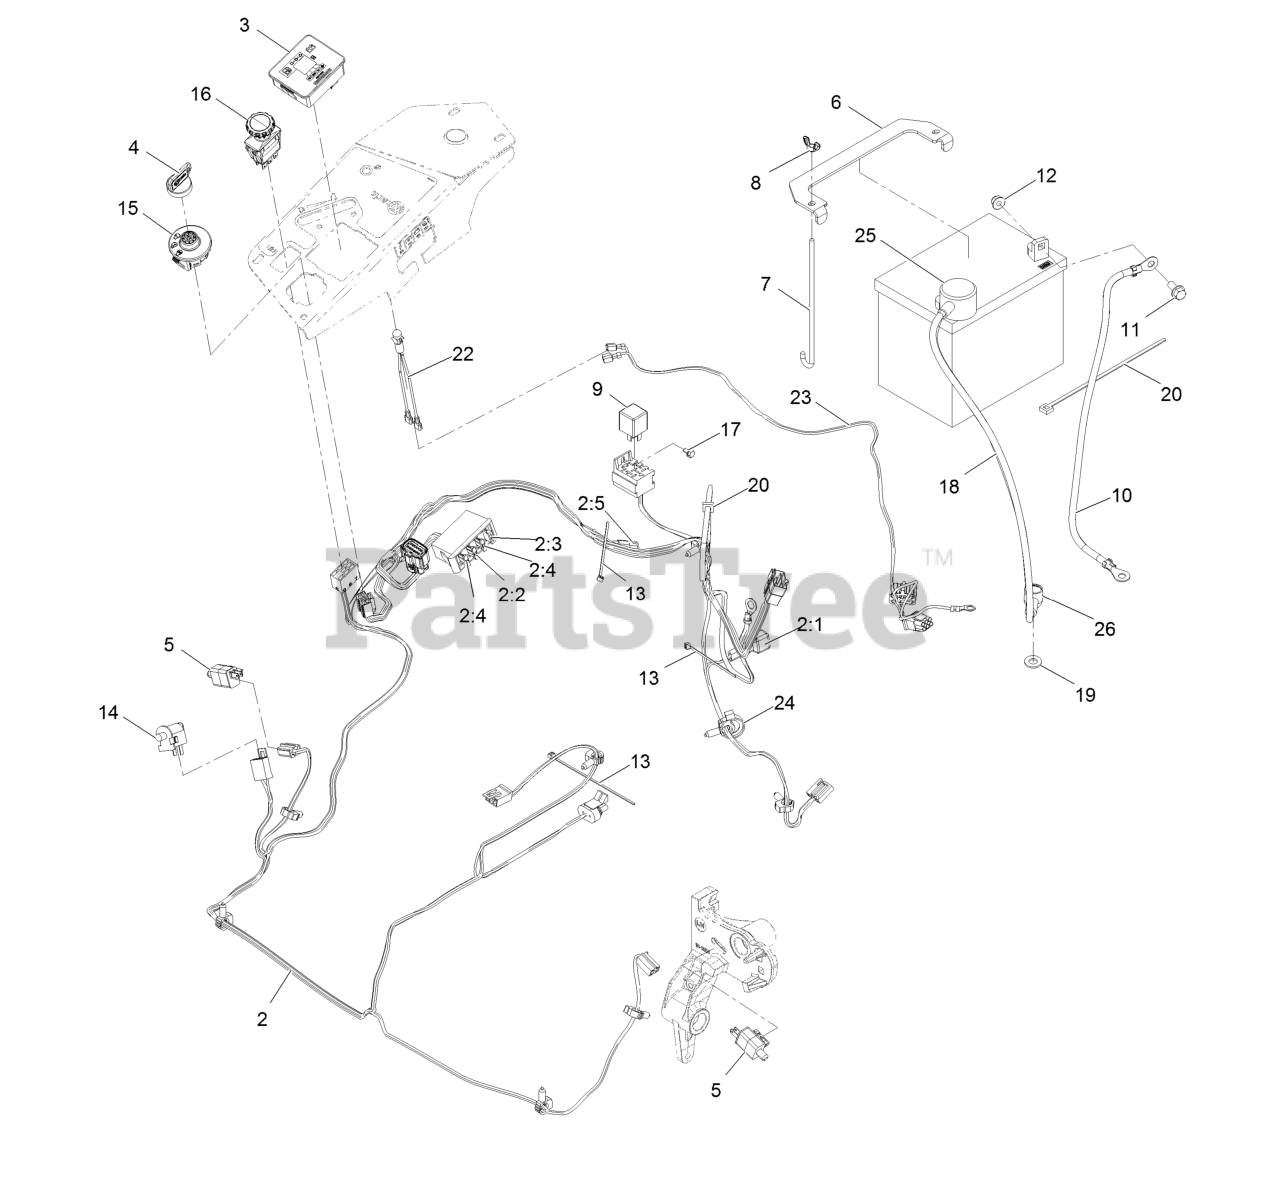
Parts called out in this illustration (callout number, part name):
2	HARNESS-WIRE, MAIN
2:2	FUSE-BLADE, 10 AMP
2:3	FUSE-BLADE, 15 AMP
2:4	FUSE-BLADE, 25 AMP
2:5	CAP-PLUG
3	FUEL/HOUR METER ASM
4	KEYS-IGNITION (SPARE PAIR
4	KEY-IGNITION
6	STRAP-TIE DOWN, BATTERY
7	BOLT-HOLDDOWN
8	WINGNUT
10	CABLE-BATTERY, NEGATIVE
11	SCREW-HHF
12	NUT-HF, NI
13	TIE-CABLE
14	SWITCH-BAIL
16	SWITCH-PTO, 10 AMP
17	SCREW-HWH
18	CABLE-BATTERY, POSITIVE
19	WASHER-FLAT
20	TIE-PLASTIC
22	INDICATOR-LED, RED
23	HARNESS-LIGHT, INDICATOR
24	CLAMP-HOSE
25	INSULATOR-BATTERY
26	INSULATOR-SOLENOID
